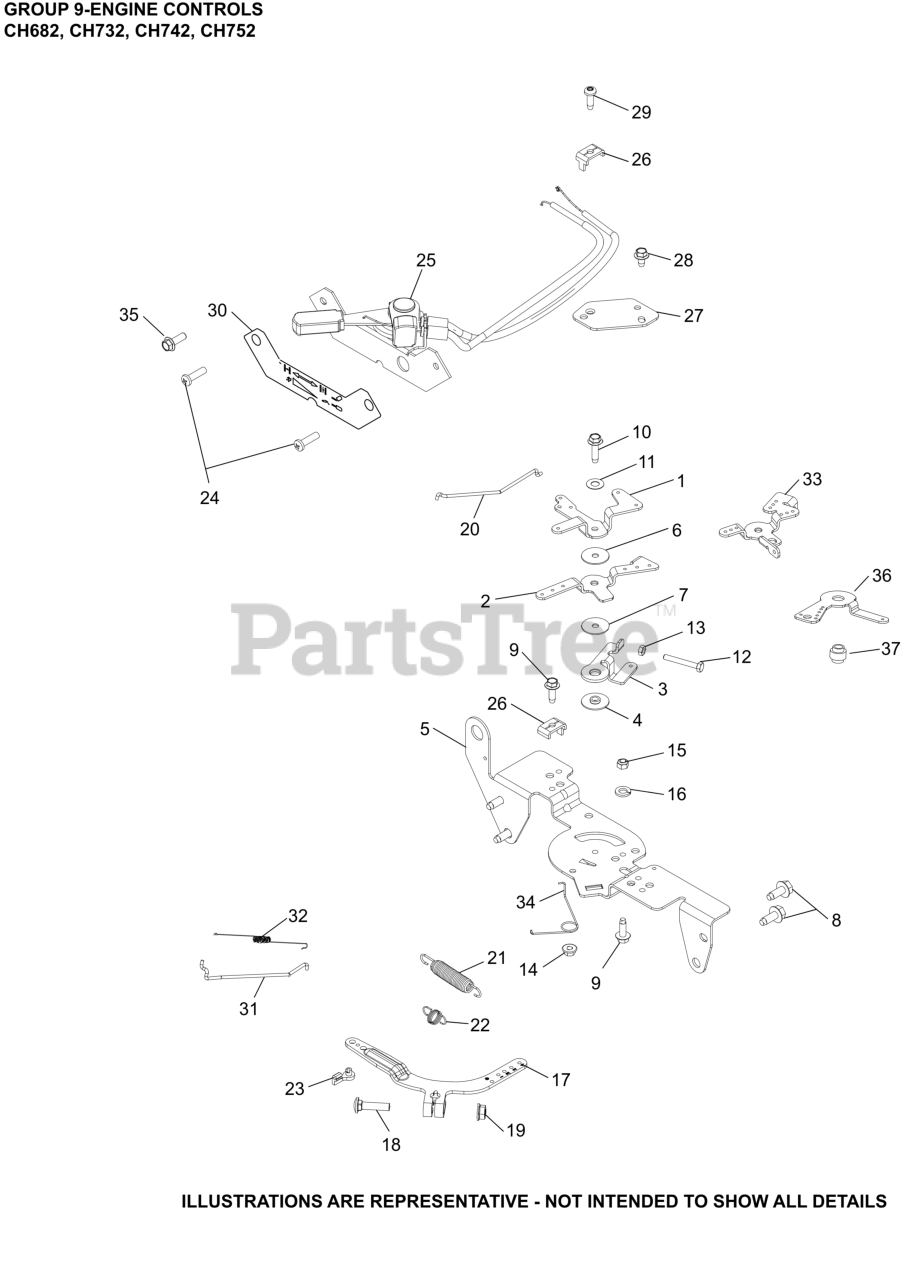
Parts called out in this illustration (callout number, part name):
1	LEVER, CHOKE
2	LEVER, THROTTLE CONTROL
3	LEVER, THROTTLE ACTUATOR
4	SPACER, CONTROL ASSEMBLY
5	BRACKET, CONTROL
6	WASHER, FLAT 5.5 MM
7	WASHER, FLAT 5 MM
8	SCREW, THREAD FORMING
9	SCREW, THREAD FORMING
10	SCREW, THD FRM-USE 25 086 473-S
11	WASHER, SPRING 1/4"
12	SCREW, CAP M4X.7X30
13	NUT, M4X0.7
14	NUT, FLG M5X.8
15	NUT, LOCK M5X.8
16	WASHER, SPRING LOCK 1/4"
17	LEVER, GOVERNOR - (#2409069S)
17	LEVER, GOVERNOR ASSEMBLY
18	BOLT, RD HD SQ NECK M6X1.0X25
19	NUT, FLG M6X1.0
20	LINKAGE, CHOKE
21	SPRING, GOVERNOR (RED)
22	SPRING, GOVERNED IDLE
23	BUSHING, THROTTLE LINKAGE
25	CABLE, CONTROL ASSEMBLY
26	CLAMP, CABLE
27	BRACKET, CABLE SUPPORT
28	SCREW, THREAD FORMING
29	SCREW, THREAD FORMING
30	DECAL, CONTROL PANEL
31	LINKAGE, THROTTLE
32	SPRING, LINKAGE
35	SCREW, HI-LOW
